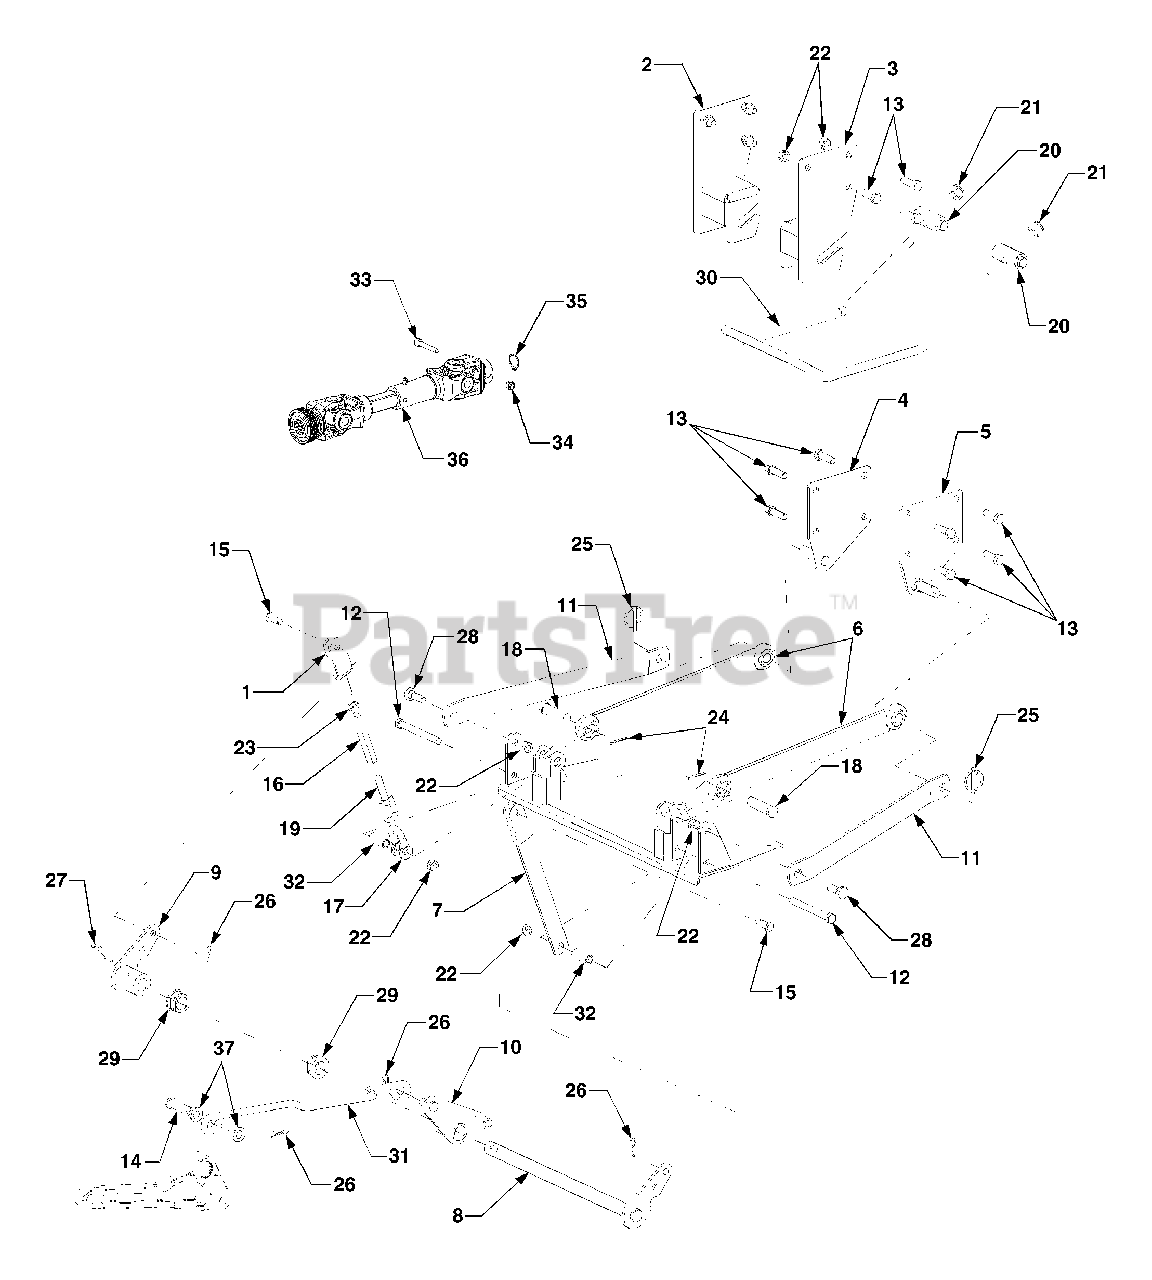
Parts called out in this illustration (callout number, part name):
1	Clevis, Adjustment, 1/2 -13 x 4.76
2	Bracket, Front Hanger LH
3	Bracket,, Front Hanger RH
4	Bracket, Rear Hanger LH
5	Bracket, Rear Hanger RH
6	Link, Deck Lift
10	Plate, Lift Crank
11	Brace, Deck Side
12	Screw, Hex Cap, 1/2-13 x 4.5 GR5
13	Screw, Hex Cap, 1/2-13 x 1.5 GR5
14	Pin, Clevis, .625 x 2.4
15	Pin, Clevis, .5 x 1.18
16	Turn Buckle, Hex Adjustment
17	Clevis, Check Chain
18	Pin, Clevis, 3/4 x 2.5
19	Clevis, Chain
20	Pin, Hanger Rod Mounting
21	Nut, Hex Insert Lock, 5/8-11
22	Nut, Hex Center Lock, 1/2-13
23	Nut, Hex Jam, 1/2-13 GR5
24	Pin, Cotter, 3/16 x 1.5
25	Pin, Klik
26	Pin, Internal Cotter
27	Pin, Spirol, 5/16 x 1.75
28	Screw, Shoulder, .625 x.36: 1/2-13
29	Bearing, Flange w/Flats
30	Rod, Front Hanger
31	Rod, Crank Lift
32	Spacer, .52 x .87 x 1.57
33	Screw, Socket Hex, 5/16-18 x 1.75
34	Nut, Hex Insert Lock, 5/16-18
35	Ring, Retaining
36	Shaft, Drive
37	Washer, Flat, .635 x 1.125 x .09
